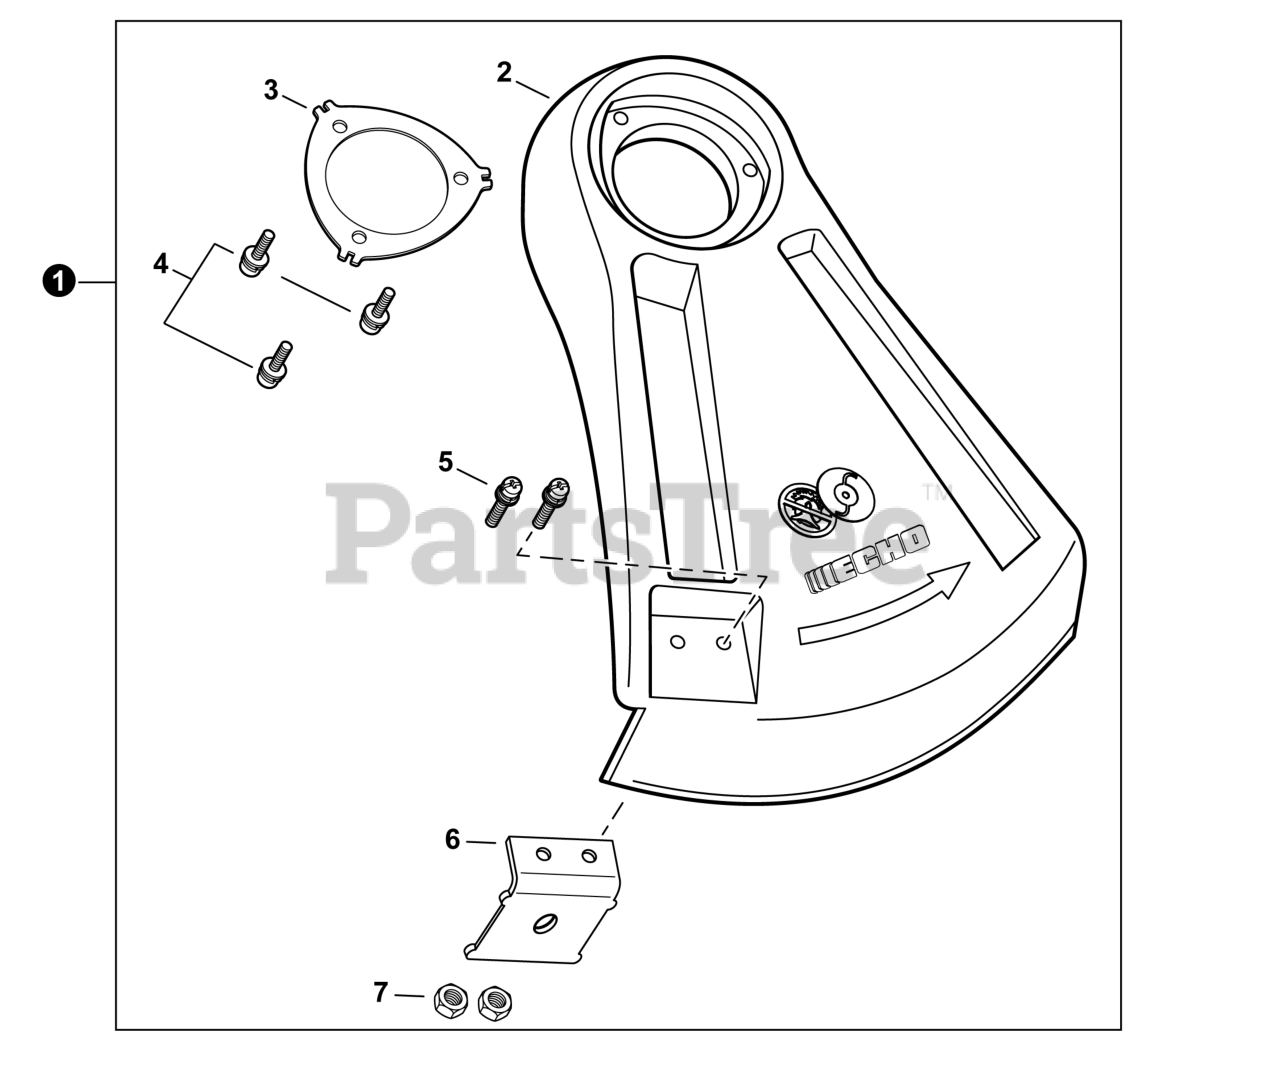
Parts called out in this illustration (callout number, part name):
1	SHIELD KIT, DEBRIS
2	SHIELD, DEBRIS PLASTIC
3	PLATE, SHIELD
4	SCREW 5x16
5	SCREW 5x12
6	CUTTER, LINE
